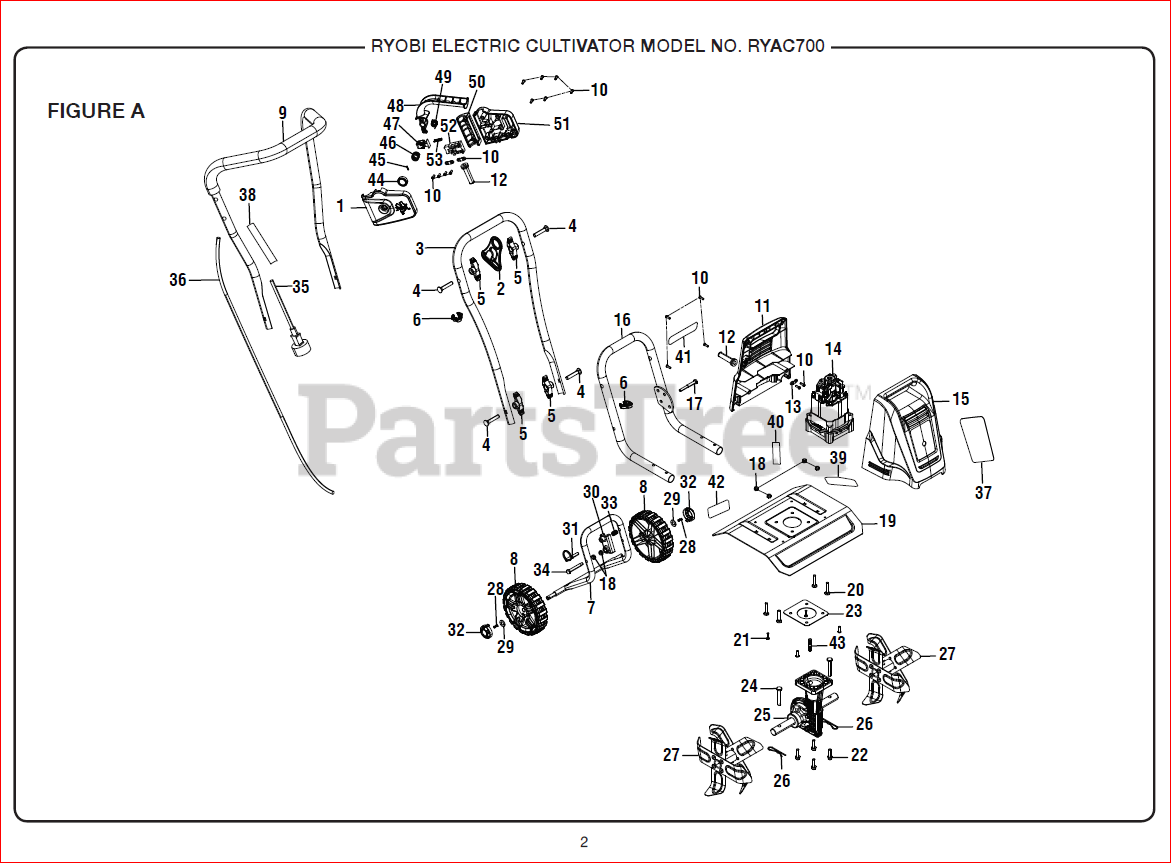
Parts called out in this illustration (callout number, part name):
1	Switch Box (Upper)
2	Cord Retainer
3	Lower Handle
4	Carriage Bolt (M8 x 45 mm)
6	Cord Hook
7	Wheel Height Adjusting Assembly
8	Wheel Assembly
9	Upper Handle Assembly
10	Screw (M4 x 12 mm, Pan Hd.)
11	Motor Housing (Rear)
12	Bend Relief
13	Cord Clamp
14	Motor Assembly
15	Motor Housing (Front)
16	Handle Frame (Lower)
17	Bolt (M6 x 50 mm, Hex Hd.)
18	Lock Nut (M6)
19	Blade Shield
20	Carriage Bolt (M6 x 35 mm)
21	Screw (M5 x 16 mm, Pan Hd.)
22	Screw (M6 x 25 mm, Pan Hd.)
24	Clevis Pin
25	Transmission Assembly
26	Cotter Pin
27	Blade Assembly
28	Steel Hook
29	Washer (ID10 x OD18 x 1.5t)
30	Angle Adjustment Plate
32	Wheel Hub
33	Compression Spring (Pulling Rod)
34	Bolt (M6 x 50 mm, Hex Hd.)
35	Power Cord w/Plug
36	Power Cord
37	Logo Label
38	Icon Warning Label
39	Warning Label (French/Spanish)
40	No Hands/No Feet Label
41	Data Warning Label
42	Wheel Adjustment Label
43	Flex Shaft
44	Switch Button
46	Compression Spring (Switch Button)
47	Switch Push Rod
49	Torsion Spring (Trigger Lever)
50	Handle Fixing Plate
51	Switch Box (Lower)
53	Compression Spring (Switch Push Rod)
